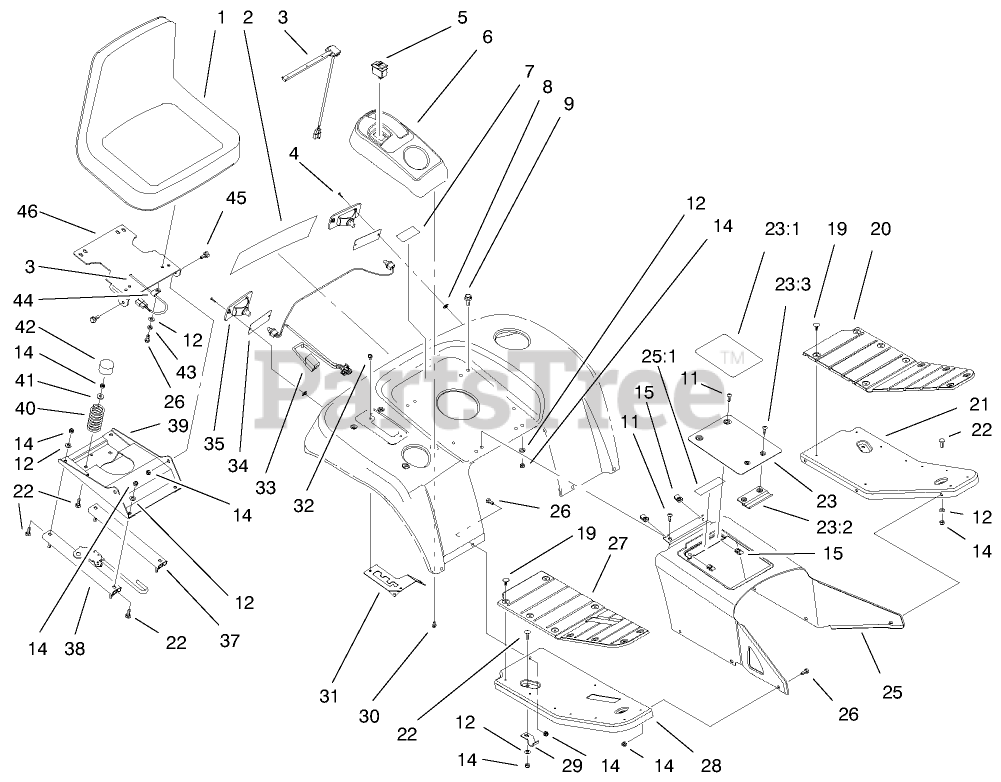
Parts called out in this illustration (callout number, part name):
3	SWITCH-SEAT
4	SCREW-PPH
5	SWITCH-CRUISE
6	POD-CONTROL
6	POD - CONTROL INT'L
6	POD - CONTROL 18 HP
7	DECAL - USA
8	NUT-SPEED
9	SCREW-HHF
11	SCREW-HH
12	WASHER-PLAIN
14	NUT-LOCK, NI
16	DECAL-DANGER
19	FASTENER-PANEL
20	PAD-FOOTREST, LH
21	FOOTREST-LH
22	SCREW-CARR
23	ASM - TUNNEL COVER TORO
23	TUNNEL COVER ASM
23:1	DECAL - DANGER
23:2	RETAINER-COVER
23:4	SCREW-PPH
25	Tunnel ASM (Only On: 73470, 73540)
25	Tunnel ASM (Only On: 73541)
25:1	DECAL-DANGER
25:1	DECAL - WARNING
26	SCREW-HH
28	FOOTREST-RH
29	BRACKET-FOOTREST
30	SCREW-HWH
31	GATE-HI / LO SHIFT
32	SCREW-HWH
33	HARNESS - REAR
35	LAMP-TAILLIGHT
35	REFLECTOR
37	SLIDE-SLAVE, SEAT
38	SLIDE-LATCH, SEAT
40	SPRING-COMPRESSION
41	BUSHING
42	CAP-SPRING, SEAT
43	WASHER-LOCK
44	CLAMP-R
45	BOLT-SHOULDER,HFH
